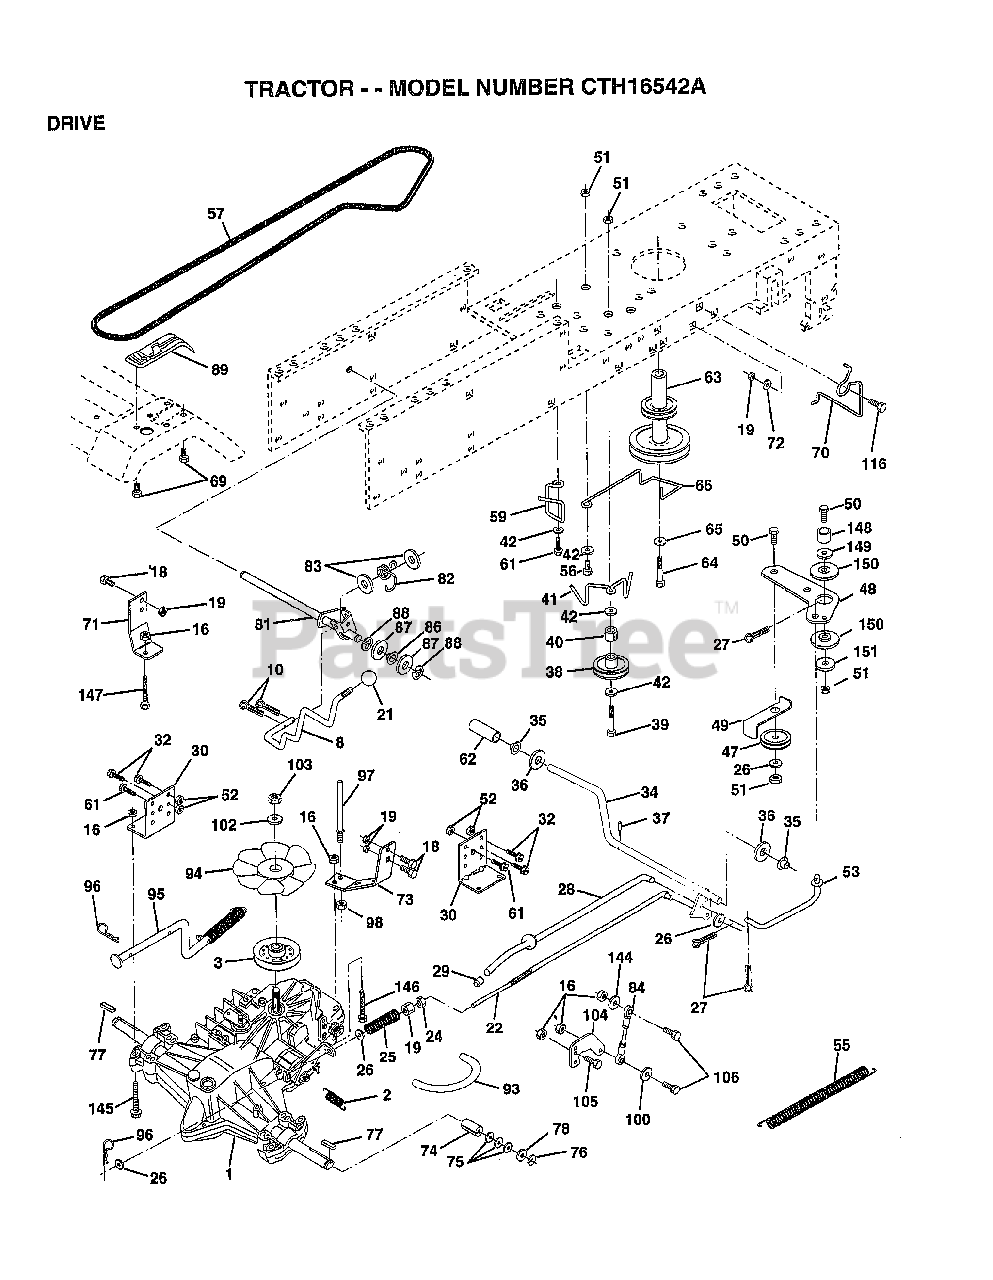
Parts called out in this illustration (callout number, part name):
1	TRANSAXLE.3100650
2	SPRING RET BRAKE
3	PULLEY.TRANSAXLE
8	ROD SHIFT FEND LT
10	PIN COTTER 1/8
16	NUT
18	BOLT
19	NUT
21	KNOB DLX BLK/BLK
22	ROD.BRAKE.HYDRO.
24	NUT
25	SPRING ROD LT
26	WASHER
27	COTTER PIN
28	ROD.BRAKE.PARK.LT
29	PLUNGER CAP T
30	TRANSAXLE MTG BKT
32	BOLT
34	SHAFT ASM-PEDAL F
35	NYLON BEARING
36	WASHER LT
38	PULLEY.IDLER.FLAT
39	BOLT
40	SPACER T
42	WASHER
48	BELLCRANK.CLUTCH
49	RETAIN BELT
53	"LINK, CLUTCH T"
55	"SPRING, RETURN LT"
57	V-BELT.GROUND.HYD
59	KEEPER BELT CNTSP
61	SCREW
62	PEDAL COVER T
63	PULLEY.ENGINE
64	BOLT
65	LOCKWASHER
66	ENGINE BELT KEEPR
69	SCREW HEXWSH H-L
71	STRAP TORQ LH HYD
72	WASHER
73	"STRAP-TORQUE,RH"
74	SPACER SPLIT
76	E-RING LT
77	SQUARE KEY
78	WASHER
81	SHAFT.ASM.CROSS
82	"SPRING,TORSION"
83	WASHER
84	ROD.TIE
86	BUSHING
87	WASHER D
88	KLIP RING
93	"LINE FUEL HYD 4"""
94	"FAN 7"" HYDRO"
97	BOLT KEEPER RH
98	NUT
100	WASHER M
102	WASHER BELLEVILLE
104	ARM CONTROL HYDRO
105	SCREW CAP 5/16-18
106	BOLT
116	BOLT RDHD 3/8-16
144	WASHER
145	BOLT.HEX.FLGHD
146	BOLT.HEX.FLGHD.
147	BOLT.HEX.FLGHD
149	SPACER RETAINER
150	BUSHING.NYLON
151	WASHER
